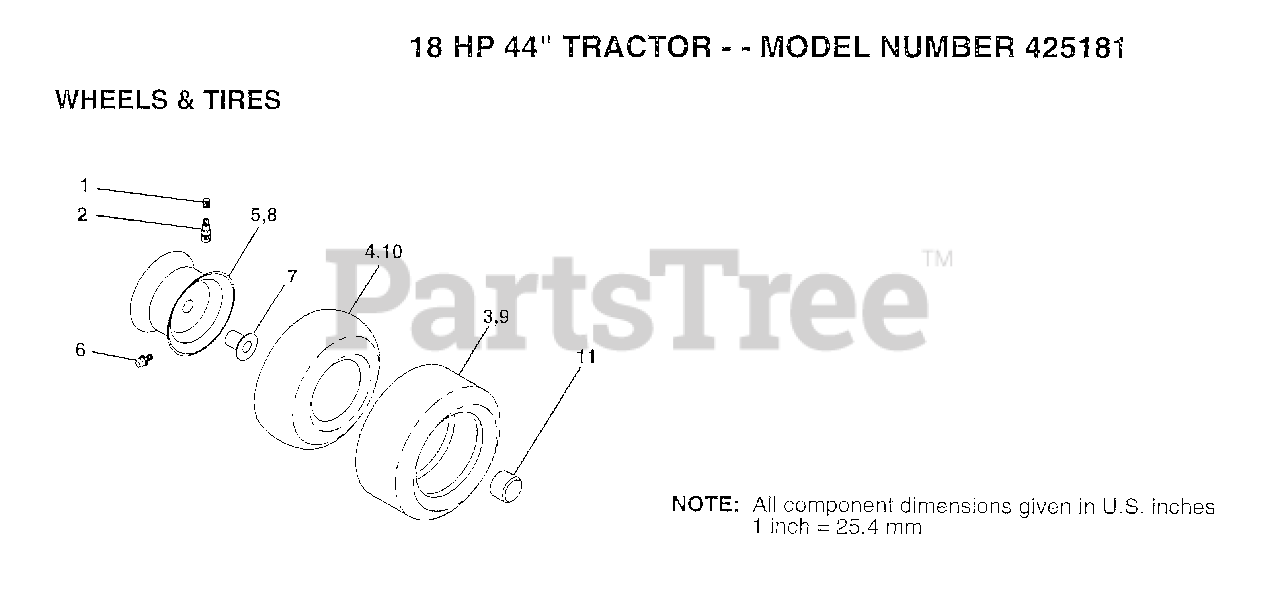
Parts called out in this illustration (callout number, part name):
1	VALVE CAP
2	VALVE STEM LT
4	TUBE.5.3/4.5/6
5	RIM.FRONT.
6	FITTING LT
7	"FLANGE, BEARING"
8	RIM.REAR.417
10	TUBE.23X8/10-12
11	HUB CAP
